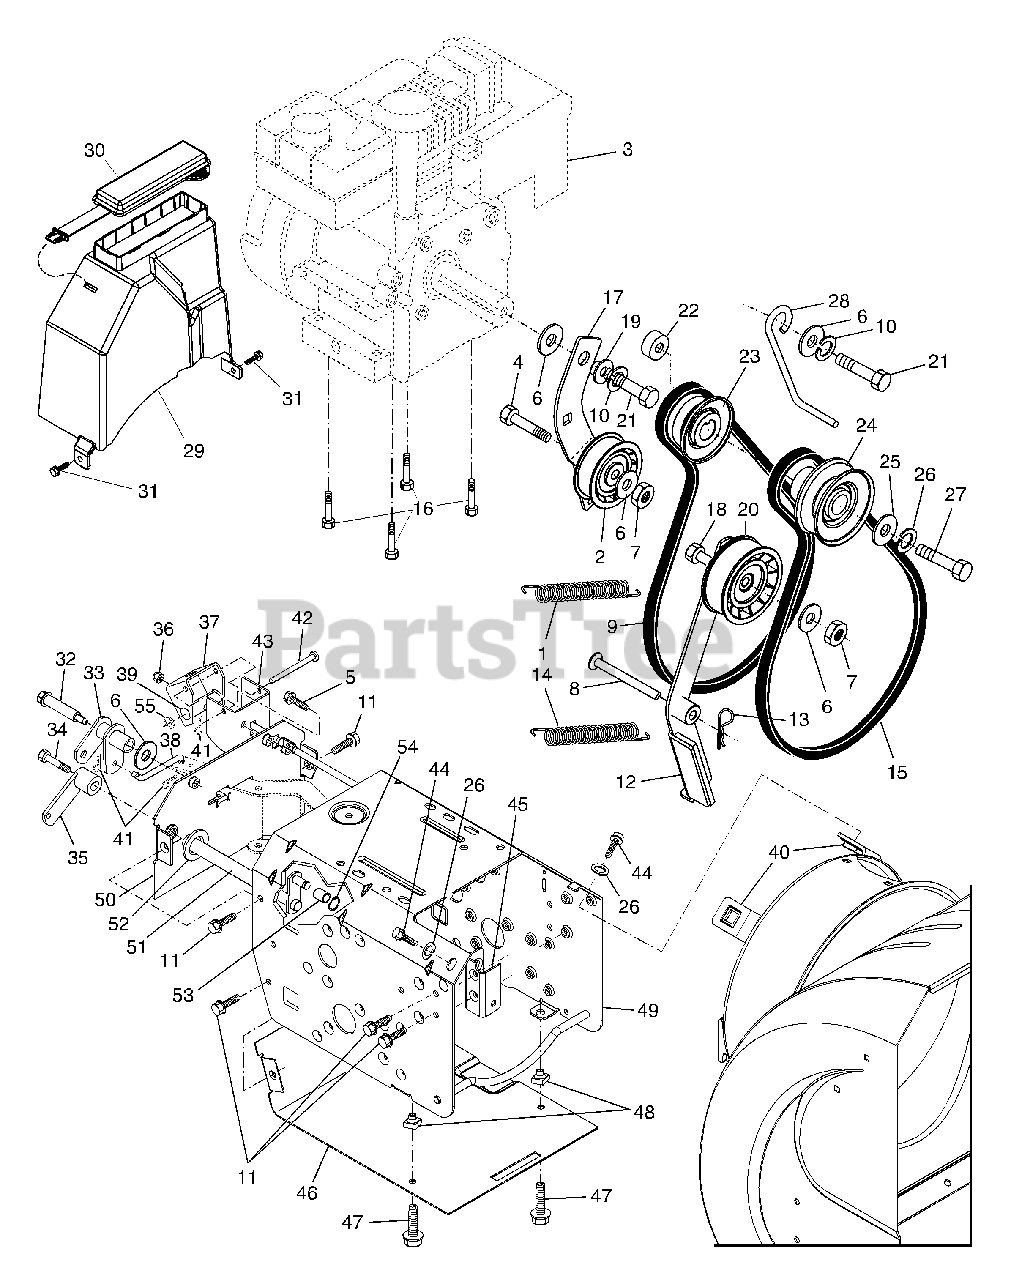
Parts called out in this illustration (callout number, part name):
1	Spring, Traction Idler
2	Pulley, Idler (2-1/4)
4	Screw, Hex Head 5/16-18 x 1-1/4
5	Screw, Hex Washer Head 5/16-18 x 3/4
6	Washer, Flat
7	Nut, Jam, Lock 5/16-18
8	Pin, Idler Pivot
9	V-Belt, Traction Drive
10	Washer, Lock 5/16
11	Screw, Hex Washer Head 5/16-18 x 1/2
12	Impeller Idler Arm Assembly
13	Retainer, Hairpin
14	Spring, Brake
15	V-Belt, Impeller Drive
16	Screw, Hex Head 3/8-16 x 1-1/4
17	Arm, Idler
18	Screw, Hex Head 5/16-18 x 1-1/2
19	Bushing, Idler Pivot
20	Pulley, Idler (2-3/4)
21	Screw, Hex Head 5/16-24 x 1
22	Spacer, Engine Pulley
23	Pulley, Engine, Traction Drive
24	Pulley, Engine, Impeller Drive
25	Washer, Flat 3/8
26	Washer, Lock, Helical
27	Screw, Hex Head 3/8-24 x 1-3/8
28	Guide, Belt
29	Cover, Belt
30	Cover, Toolbox
31	Screw, Hex Head 1/4-20 x 1/2
32	Bolt, Shoulder 5/16-18
33	Bellcrank Shifter
34	Screw, Hex Head 1/4-28 x 3/4
35	Arm, Auger Control
36	Nut, Lock 5/16-18
37	Bellcrank Assembly
38	Link, Speed Control
39	Trunnion, Clutch
40	Nut, Cage 3/8-16
41	Hairpin, Cotter 3/32 x 1/2
42	Pin, Bellcrank
43	Bracket, Bellcrank
44	Screw, Hex Head 3/8-16 x 1-1/2
45	Pivot Bracket, Impeller Idler Arm
46	Pan, Frame Bottom
47	Screw, Hex Head 5/16-18 x 3/4
48	Nut, Speed 5/16-18
49	Frame Assembly
50	Plate, Frame End
51	Shaft, Auger Control
52	Washer, Hardened
53	Roller
54	Ring, Crescent
